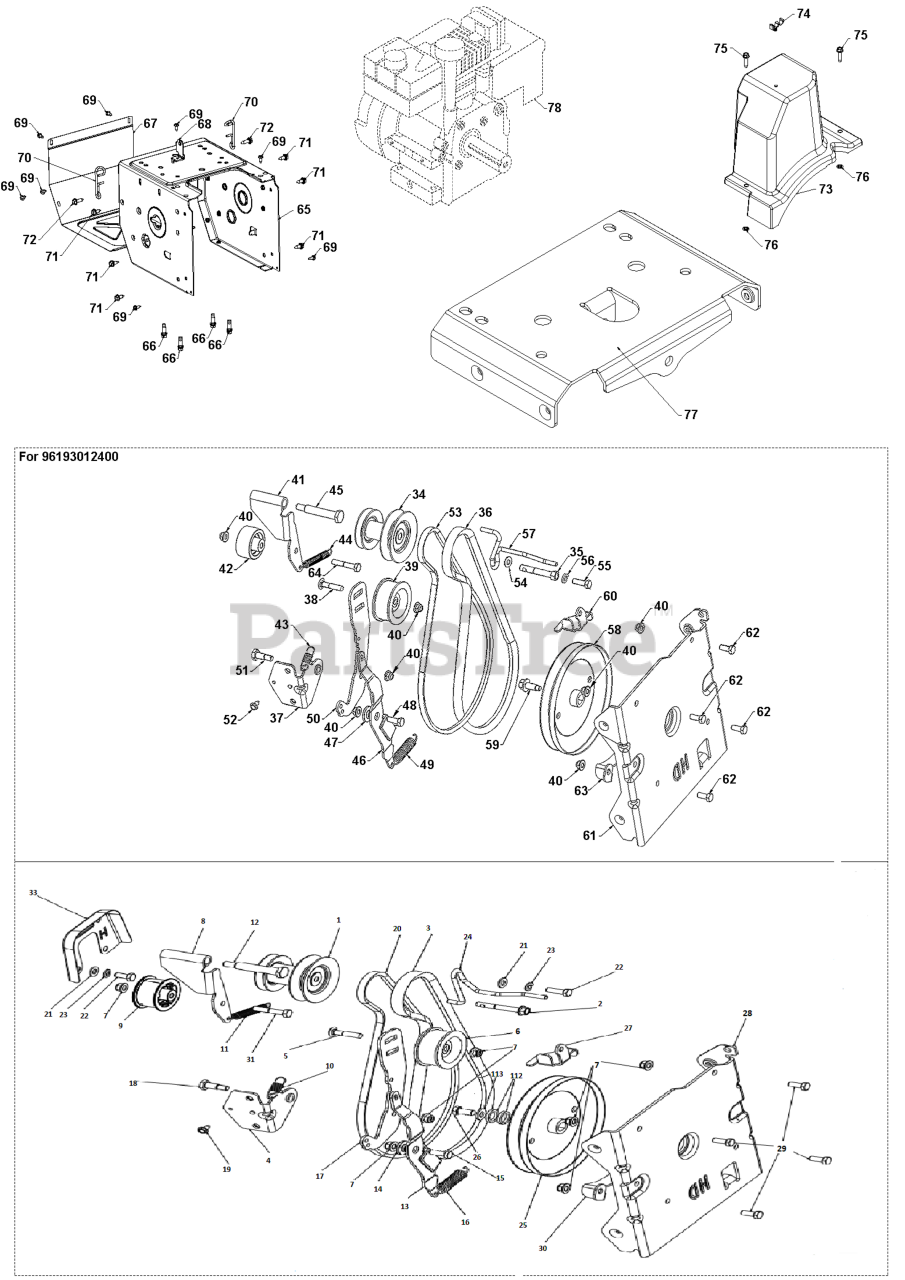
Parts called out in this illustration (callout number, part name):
1	PULLEY 5L GEAR
1	PULLEY WELDMENT
2	BOLTS
2	BOLT.ENGINE.PULLEY
3	BELT 5L 39.15L
4	BRACKET WELDMENT, IDLER ARM ZI
5	BOLT 5/16-18 CARRIAGE 1.5L
6	Pulleys
6	PULLEYIDLER.2.0.W/SPACER.CZ
7	NUT HEXAGON FLANGE 5/16-18 ST
8	ARM DRIVE IDLER CLEAR ZINC PLA
9	PULLEYIDLER.2.0.W/SPACER.CZ
10	SPRING IDLER RETURN
11	SPRING RETURN IDLER ARM
12	BOLT 5/16-24X2.25 HEX HEAD SHO
13	ARM IMPELLER BRAKE
14	BUSHING.BRAKE.ARM
15	BOLT HEXAGON BOLT 5/16-18 X 7/
16	SPRING EXTENSION - BRAKE
17	ARM IDLER BLACK ZINC
17	ARM DRIVE IDLER CLEAR ZINC PLA
18	SCREW HEX HEAD SHOULDER
20	BELT 3L 39.68; POLY CORD
21	WASHER 11/32 X 11/16 X 14 GA T
22	SCREW 5/16-24 X .75 GR5
22	SCREW
23	WASHER SPRING LOCK WASHER WITH
24	GUIDE.BELT.5L.IMPELLER.3L.DRV
25	PULLEY IMPELLER DD 5L HD
26	BOLT
26	SCREW HEXAGON HEAD FLANGE 3/8-
28	BRACKET AUGER HOUSING INTERFAC
29	SCREW HEXAGON HEAD SCREW 5/16-
30	BRACKET.BELT.KEEPER.LOWER.BLAC
31	BOLT, HEX 5/16-18X1-3/4
34	PULLEY WELDMENT
35	BOLT.ENGINE.PULLEY
36	BELT 5L 39.15L
37	BRACKET WELDMENT, IDLER ARM ZI
38	NUT HEXAGON FLANGE 5/16-18 ST
38	BOLT 5/16-18 CARRIAGE 1.5L
40	NUTNYLOK.FLRANGE.5/16-18
40	NUT HEXAGON FLANGE 5/16-18 ST
41	BRACKET WELDMENT, IDLER ARM ZI
41	ARM DRIVE IDLER CLEAR ZINC PLA
41	ARM IDLER DRIVE WELDMENT_HOT
42	PULLEYIDLER.2.0.W/SPACER.CZ
42	PULLEY.IDLER.FLNGLESS.W/SPACER
42	PULLEY.IDLER.FLANG.2.O/SPACER
43	SPRING IDLER RETURN
44	SPRING RETURN IDLER ARM
45	BOLT 5/16-24X2.25 HEX HEAD SHO
46	ARM IMPELLER BRAKE
47	BUSHING.BRAKE.ARM
48	BOLT HEXAGON BOLT 5/16-18 X 7/
48	BOLT
49	SPRING EXTENSION - BRAKE
50	ARM IDLER BLACK ZINC
51	SCREW HEX HEAD SHOULDER
53	BELT 3L 39.68; POLY CORD
54	WASHER 11/32 X 11/16 X 14 GA T
55	SCREW 5/16-24 X .75 GR5
56	WASHER SPRING LOCK WASHER WITH
57	GUIDE BELT - 3L FRICTION, 5L I
57	PULLEY IMPELLER DD 5L HD
57	GUIDE.BELT.5L.IMPELLER.3L.DRV
58	PULLEY IMPELLER DD 5L HD
59	SCREW HEXAGON HEAD FLANGE 3/8-
61	BRACKET AUGER HOUSING INTERFAC
62	SCREW HEXAGON HEAD SCREW 5/16-
63	BRACKET.BELT.KEEPER.LOWER.BLAC
64	BOLT, HEX 5/16-18X1-3/4
65	FRAME MS 668
66	BOLT 3/8-16X1-1/8
67	COVER COVER.FRAME MS668 ORANGE
68	BRACKET.SHIFTER.BZP
69	SCREW.HEX HEAD W/COLLAR 1/4-20
70	WIREFORM.SUPPORT.CABLE
71	BOLT.HEX.HD.WASHER.5/16-18X.75
72	SCREW HEXAGON HEAD WITH COLLAR
73	COVER BELT ASM HIGH CRANK
75	SCREW HEX WASH THDRL BLK 1_4-
76	PALNUT 1/4
77	BRACKET.FRAME.SUP.LARGEENG.BLA
77	BRACKET.FRAME.SUPPORT.BLACK
78	ENGINE.LCT.369CC.ALT.SNO.16
78	ENGINES
78	LCT ENGINE 369CC
78	Engines
78	ENGINE.LCT.369CC.SNO.16
78	ENGINE RATO 389CC (CARB)
112	WASHER PLAIN WASHER 3/8 X 0.08
113	WASHER.SPACER.MANDREL
